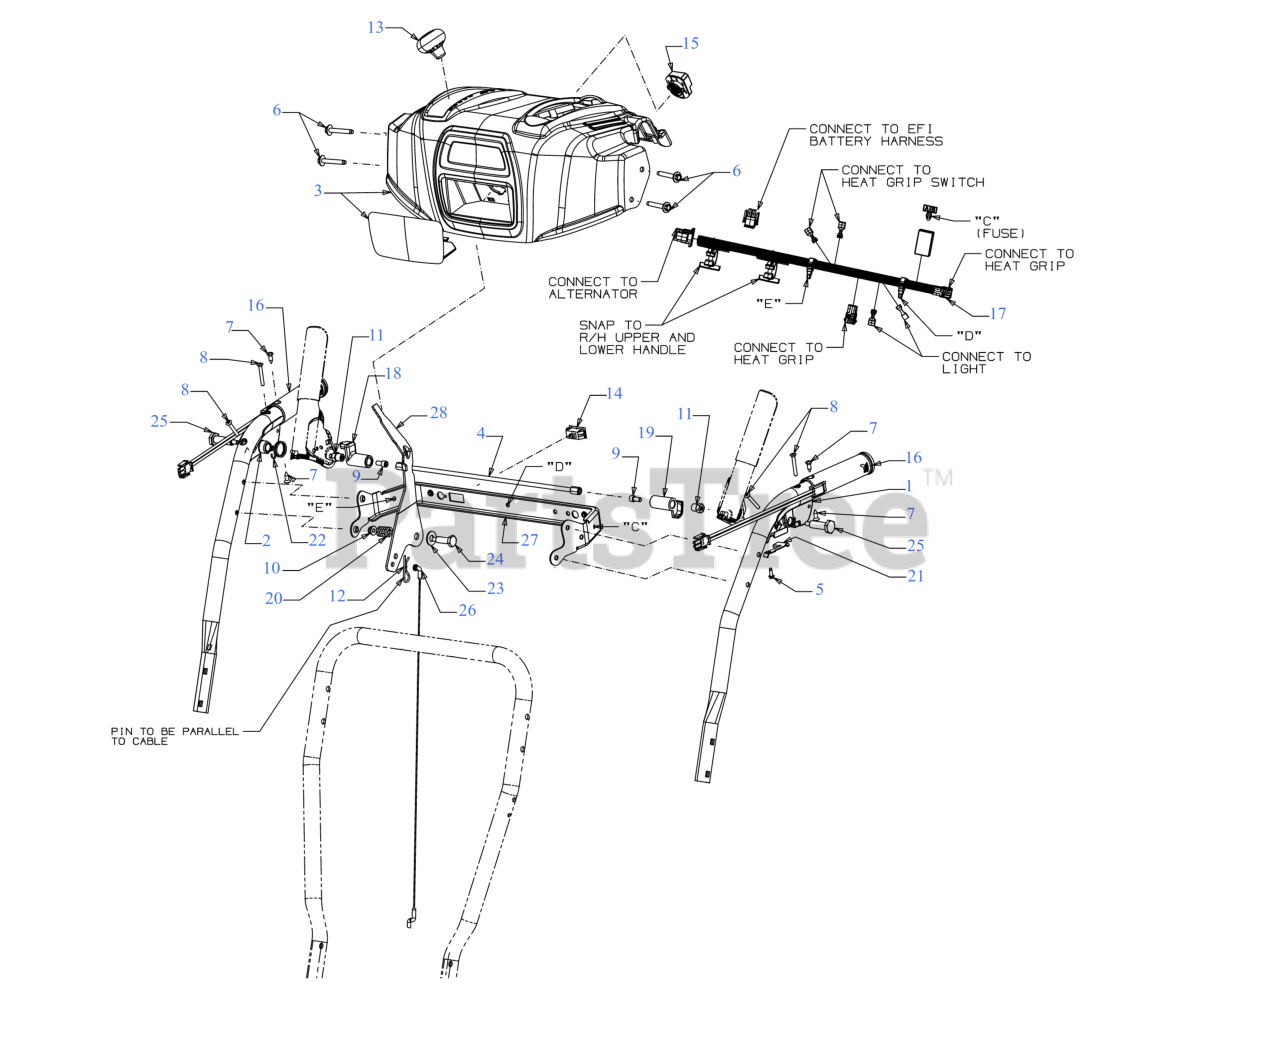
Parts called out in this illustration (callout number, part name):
1	CLUTCH LOCK HANDLE ASSEMBLY (LH)
2	CLUTCH LOCK HANDLE ASSEMBLY (RH)
3	HANDLE PANEL ASSEMBLY
4	PIVOT ROD
5	SCREW #8-16 x .50
6	SCREW 1/4-20 x 1.625
7	SCREW-AB #12-24 x .625
8	SCREW #10-24 x 1.375
9	SCREW 1/4-20 x .50
10	FLANGE LOCK NUT
11	HEX NUT W/PATCH
12	INTERNAL COTTER PIN
13	SHIFT KNOB
14	HEATED GRIP SWITCH
15	LED HEADLIGHT SOCKET (150 LUMNES)
16	HEATED GRIP
17	HARNESS (2S HG HDLT EFI)
18	LOCK PLATE
19	CLUTCH LOCK CAM
20	COMPRESSION SPRING
21	CLUTCH SPRING
22	TORSION SPRING
23	FLAT WASHER .40X.88X.060
24	SHOULDER SCREW
25	SHOULDER SCREW .437 x 1.345 1/4-20
26	SPEED SELECTOR CABLE (PLASTIC)
27	HANDLE SUPPORT BRACKET (POWDER BLACK)
